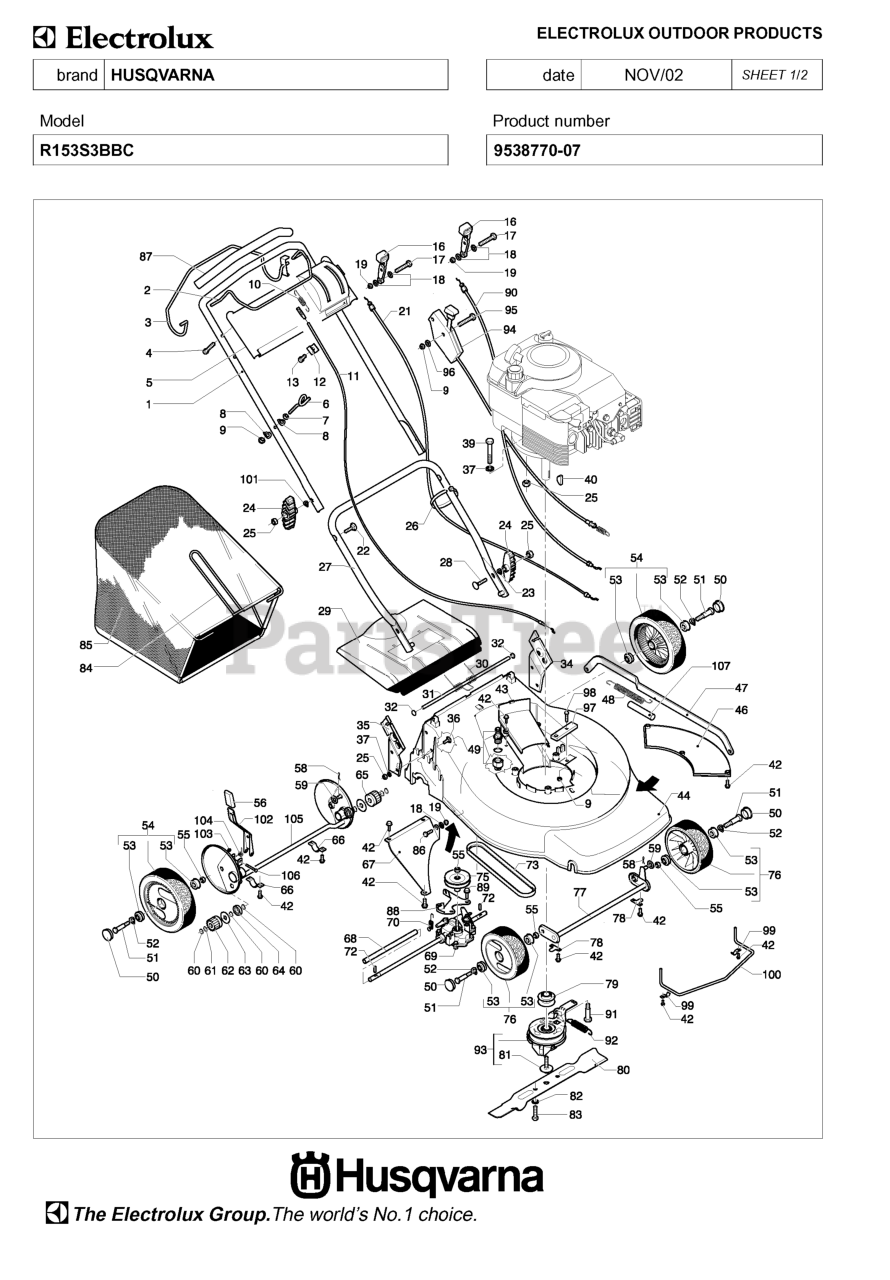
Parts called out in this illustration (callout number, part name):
28	Screws
42	Screws
58	Pins
60	Washers
